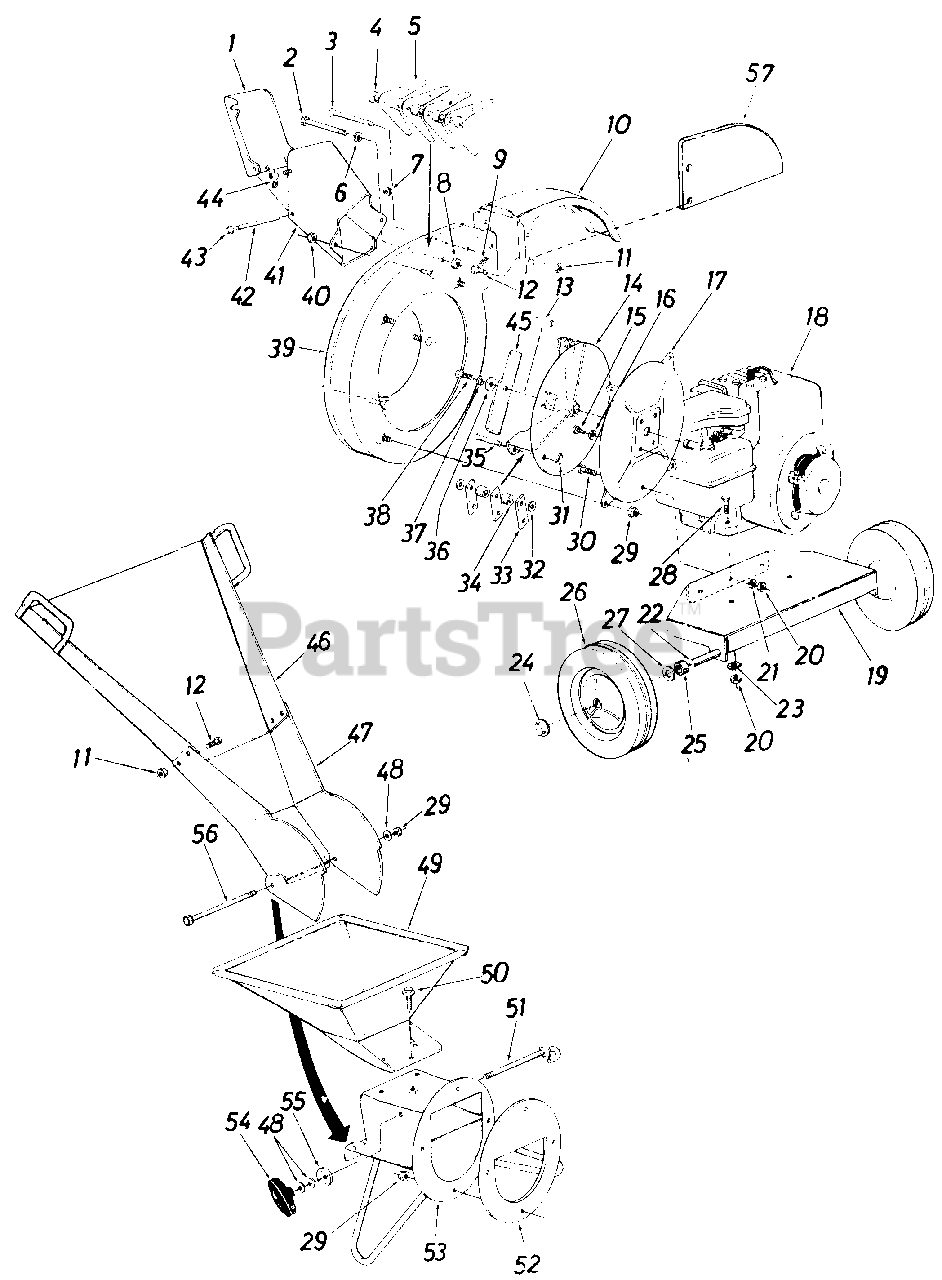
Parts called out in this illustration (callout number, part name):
1	Door Chip It
2	Hex Bolt 1/2-20 x 4.50" Lg.
3	Clevis Pin
4	Flail Spacer 7/32" Lg.
5	Cutting Finger
6	L.-Wash. 1/2" Scr.
7	Palnut 3/16" Dia.
8	Hex Jam Nut 1/2-20 Thd.
9	Cotter Pin 3/32" Dia. x 3/4" Lg.
10	Chute Deflector
11	L.-Nut 1/4-20 Thd.
12	Hex Bolt 1/4-20 x .50" Lg.
13	Sq. Key 1/4" x 2.00" Lg.
14	Impeller Assembly
15	Hex Bolt 5/16-24 x 3/4" Lg.
16	L.-Wash. 5/16" Scr.
17	Hopper To Engine Mtg. Plate
18	Engine
19	Engine Mounting Plate
20	Hex Nut 5/16-24 Thd.
21	L.-Wash. 5/16" Scr.
23	Special L.-Wash. 5/16" I.D.
26	Wheel Ass'y. - Comp.
27	Fl-Wash. .50" I.D.
28	Hex Bolt 5/16-24 x 1.50" Lg.
29	Elastic Stopnut 5/16-18 Thd.
30	Hex Bolt 5/16-24 x .62" Lg.
31	Cotter Pin 1/8" Dia. x 1.00" Lg. (Special)
32	Fl-Wash. .531" I.D. x .937 O.D x .09
33	Flail
34	Flail Spacer 23/32" Lg.
35	Clevis Pin .50" Dia. x 3.0" Lg.
36	Fl.-Wash. .406" I.D. x 1.25" O.D. Hdn.
37	L.-Wash. 3/8" Scr. H.D.
38	Hex Bolt 3/8-24 x 2.00" Lg. H.T.
41	Upper Guide Extension Ass'y.
42	Hinge Pin
43	Palnut 3/16" Dia.
44	Wing Nut Elastic 1/4-20 Thd.
47	Guide Extension
48	Fl.-Wash. 5/16" Scr.
49	Hopper Assembly
50	Hex Wash. Hd. Self-Tap Scr. 5/16-18 x .50" Lg.
51	Clamp Rod Assembly
52	Back-Up Plate
53	Inlet Guide Assembly
54	Knob Ass'y.
55	Stop Washer
56	Hex Bolt 5/16-18 x 8.38" Lg.
57	Deflector Side Plate
